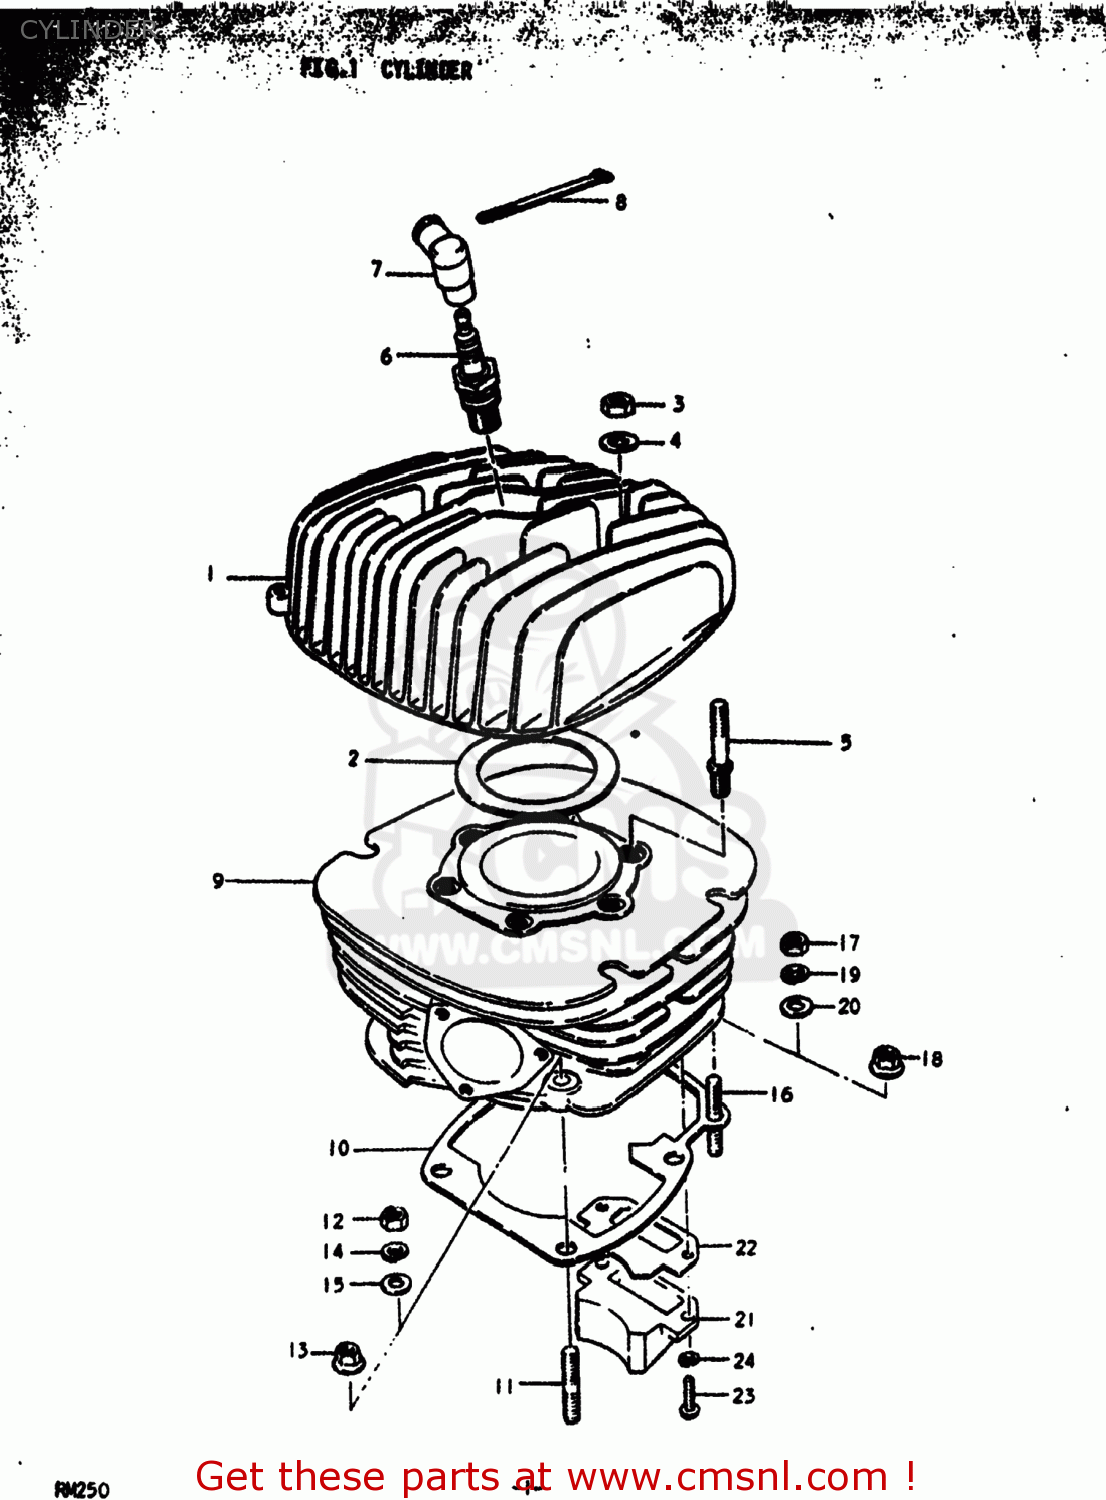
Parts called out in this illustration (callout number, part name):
1	HEAD,CYLINDER
2	GASKET,CYLINDER HEAD (NAS)
3	NUT (8MM)
4	WASHER
5	BOLT,STUD
6	SPARK PLUG
7	CAP,SPARK PLUG
8	CLAMP
9	CYLINDER
10	GASKET,CYLINDER (MCA)
11	STUD 10X25
12	NUT
13	NUT
14	LOCK WASHER
15	WASHER
16	STUD 8X25
17	NUT
18	NUT
19	LOCK WASHER
20	WASHER
21	VALVE ASSEMBLY,REED
22	GASKET,REED VALVE (MCA)
23	SCREW
24	LOCK WASHER
